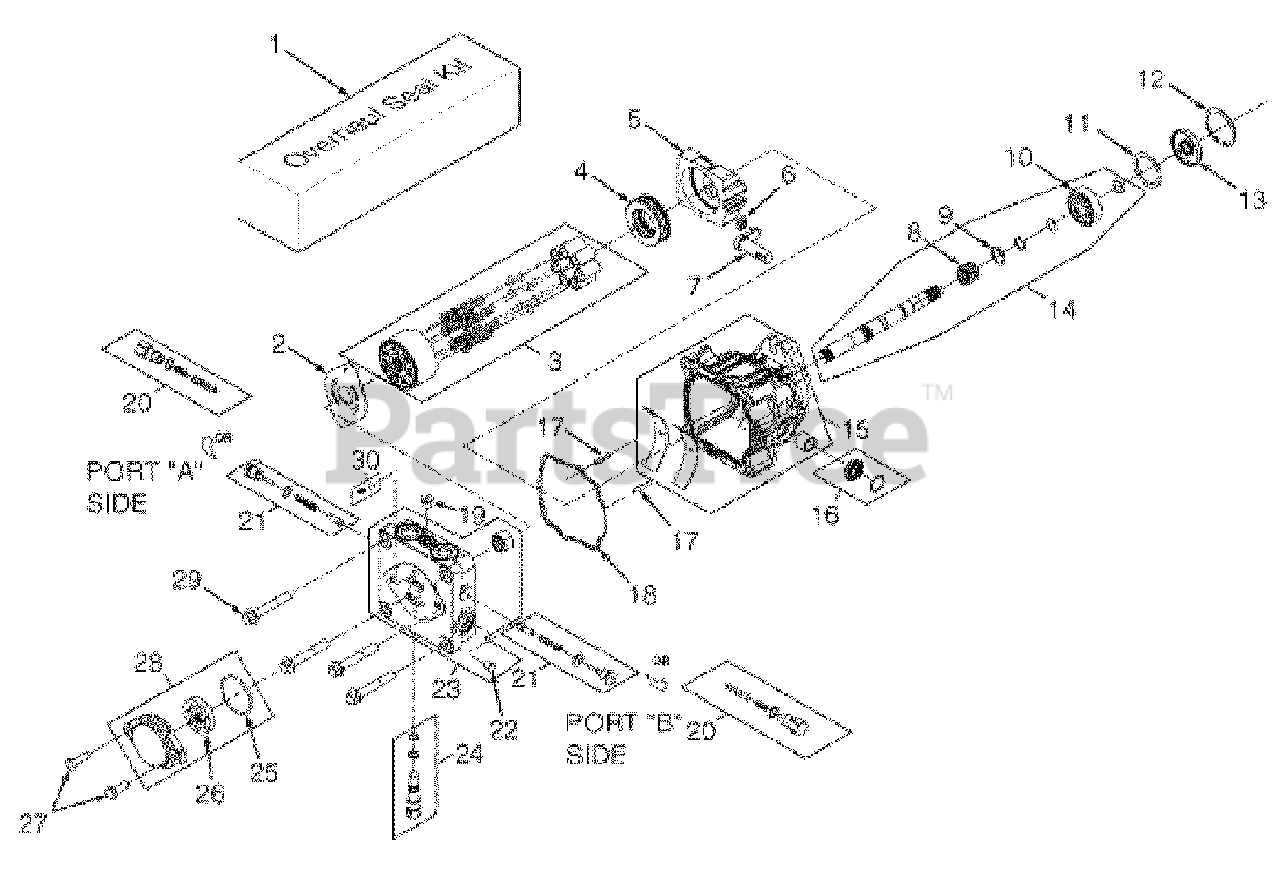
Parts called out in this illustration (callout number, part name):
1	Overhaul Seal Kit
2	Valve Plate
3	Cylinder Block Kit - 16cc
4	Thrust Ball Bearing Assembly
5	Variable Swashplate
6	Slot Guide
7	Trunnion Arm
8	Block Spring
9	Block Thrust Washer
10	Shaft Ball Bearing
12	Retaining Ring
14	Kit, Pump Shaft
15	Housing Kit
16	Trunnion Seal Kit
18	O-Ring
19	Straight Thread Plug
20	Shock Valve Kit
21	Shock Valve Kit
22	Straight Thread Plug
23	End Cap Kit
24	Bypass Valve Kit
26	Gerotor Assembly
27	Socket Head Cap Screw
28	Charge Pump Kit
29	Hex Screw, Flanged Head
30	Charge Relief Kit
